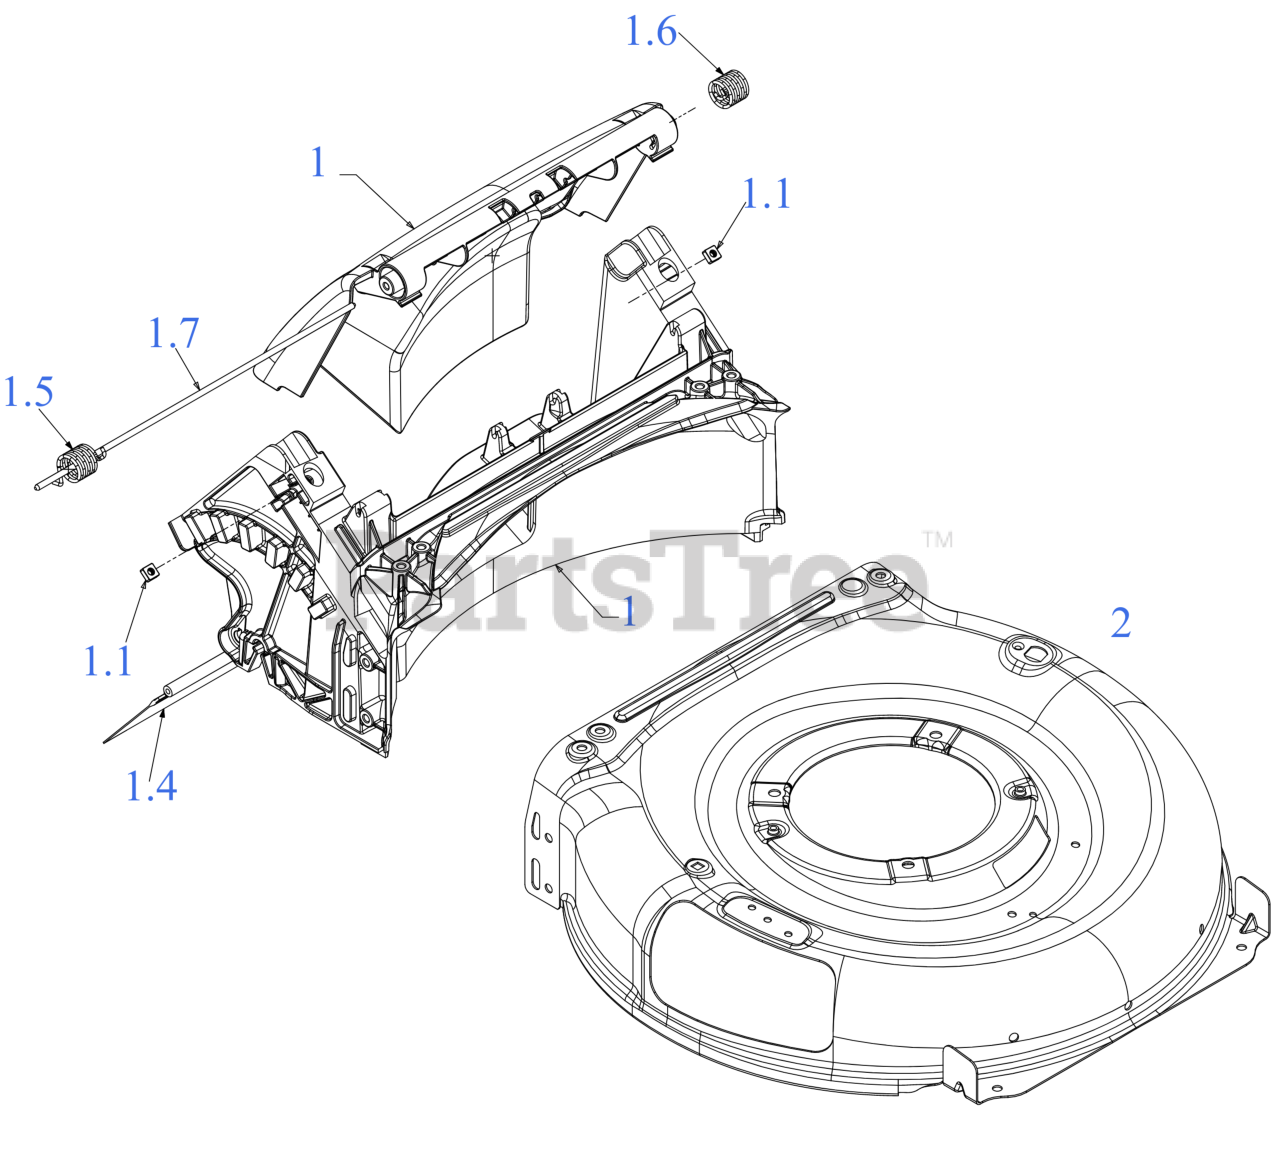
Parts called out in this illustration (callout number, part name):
1	REAR BAG DOOR ASSEMBLY
1.1	SQUARE NUT 1/4-20
1.4	TRAILSHIELD
1.5	TORSION SPRING (RH)
1.6	TORSION SPRING (LH)
1.7	REAR DOOR PIVOT ROD
